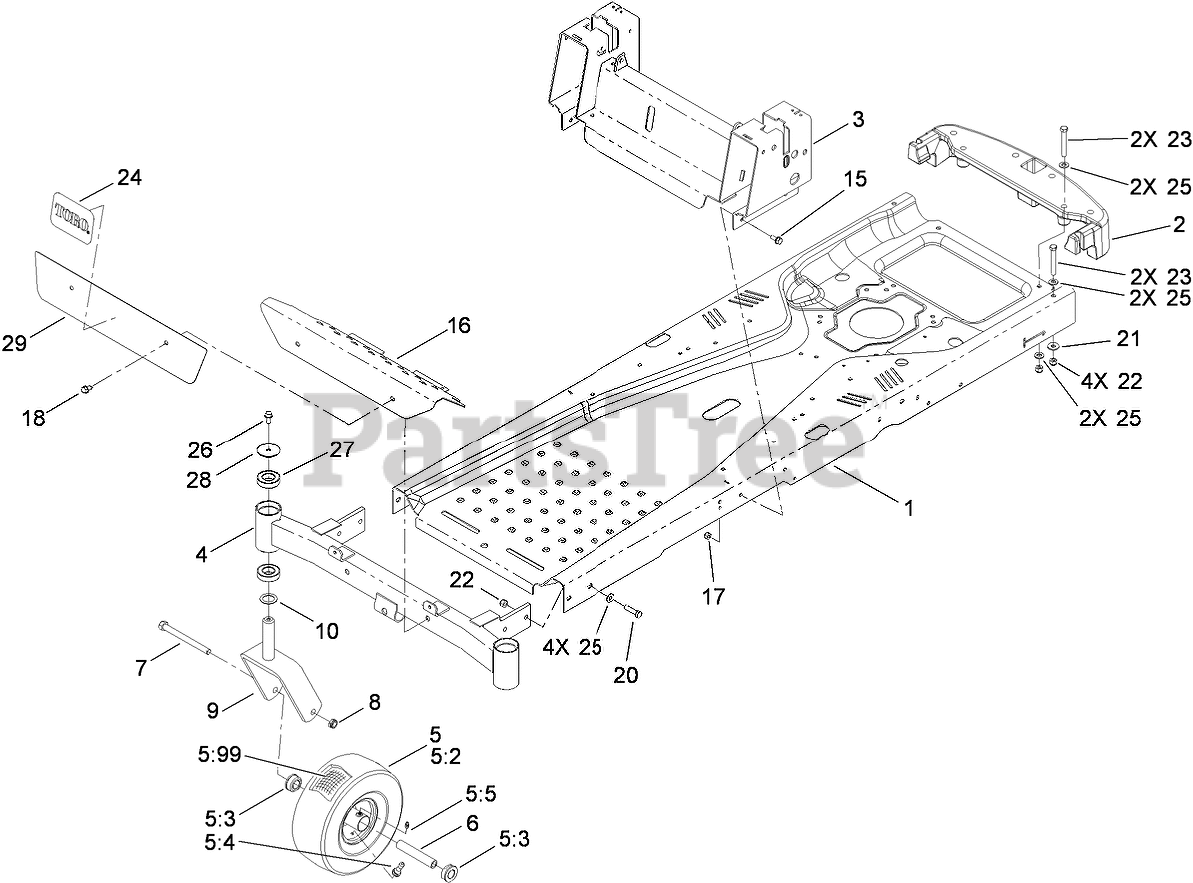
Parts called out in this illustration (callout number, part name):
2	BUMPER-REAR
3	SEAT PIVOT/CONTROL ASM
4	FRONT AXLE ASM
5	TIRE and Wheel ASM (Kenda)
5:2	TIRE-SMOOTH
5:3	BUSHING-FLANGE
5:4	STEM-VALVE
5:5	FITTING-GREASE
5:99	TUBE-INNER
6	BUSHING-SPANNER
7	SCREW-HH
8	NUT-LOCK, NI
9	CASTER FORK ASM
10	WASHER-THRUST
15	SCREW-HHF
16	FOOTREST
17	NUT-LOCK, NI
18	SCREW-HWH
20	SCREW-HH
21	WASHER-HARDENED
22	NUT-LOCK, NI
23	SCREW-HH
25	WASHER-FLAT
26	SCREW-HHF
27	BEARING-BALL
28	WASHER
29	PLATE-FOOTREST
